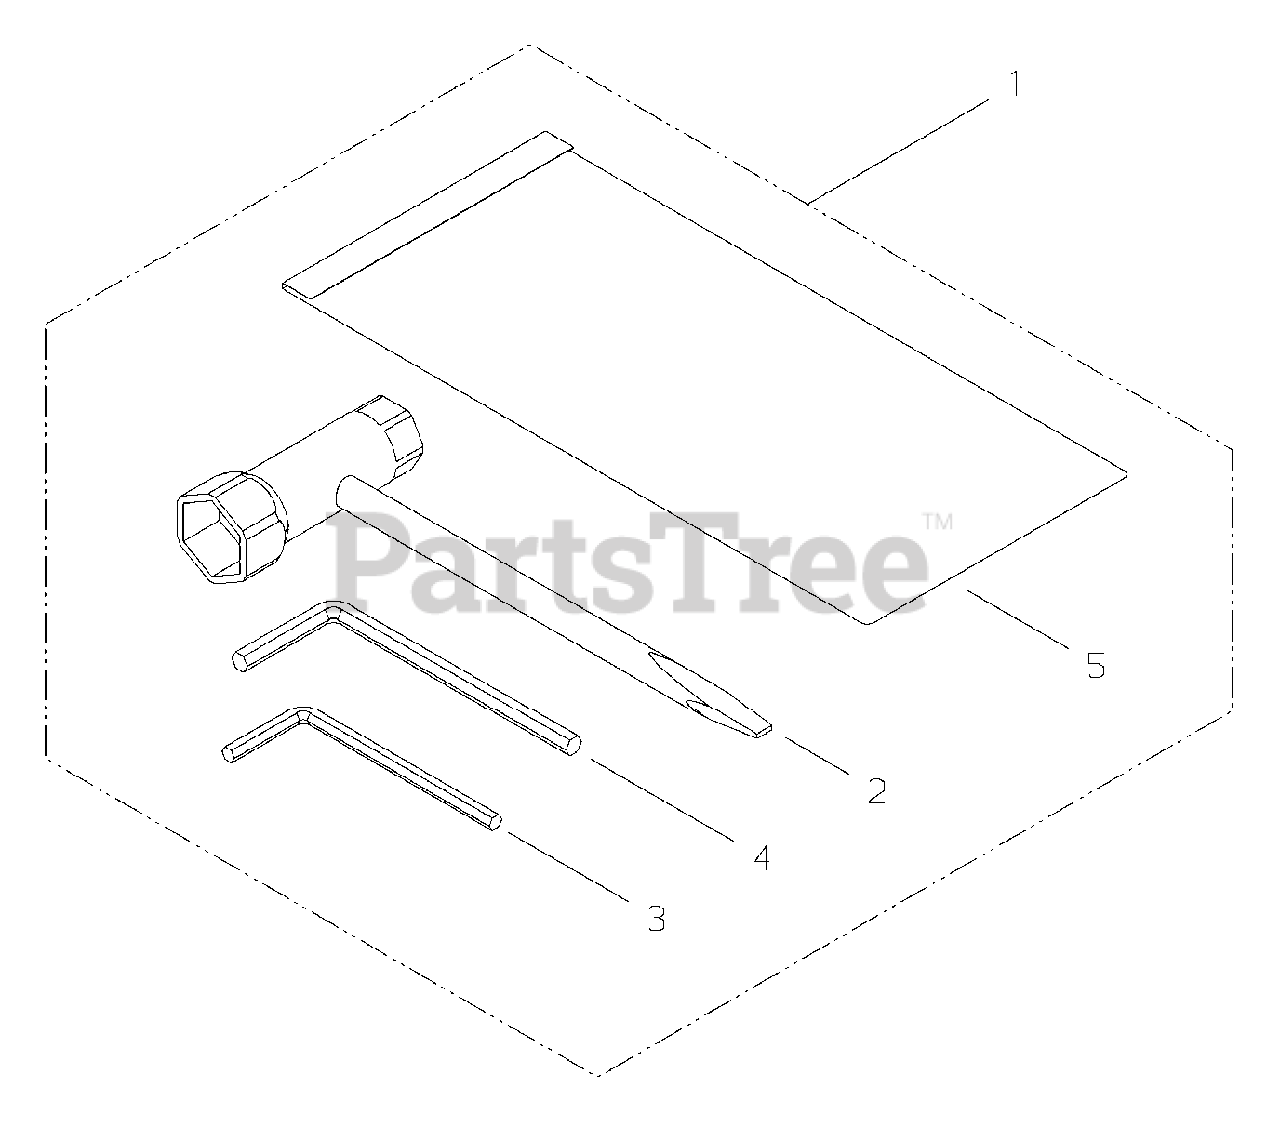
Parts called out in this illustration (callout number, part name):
1	TOOL KIT, SERVICE
2	T-WRENCH 16×13
3	WRENCH, ALLEN 4 MM
4	WRENCH, ALLEN 5 MM
5	BAG, TOOL
